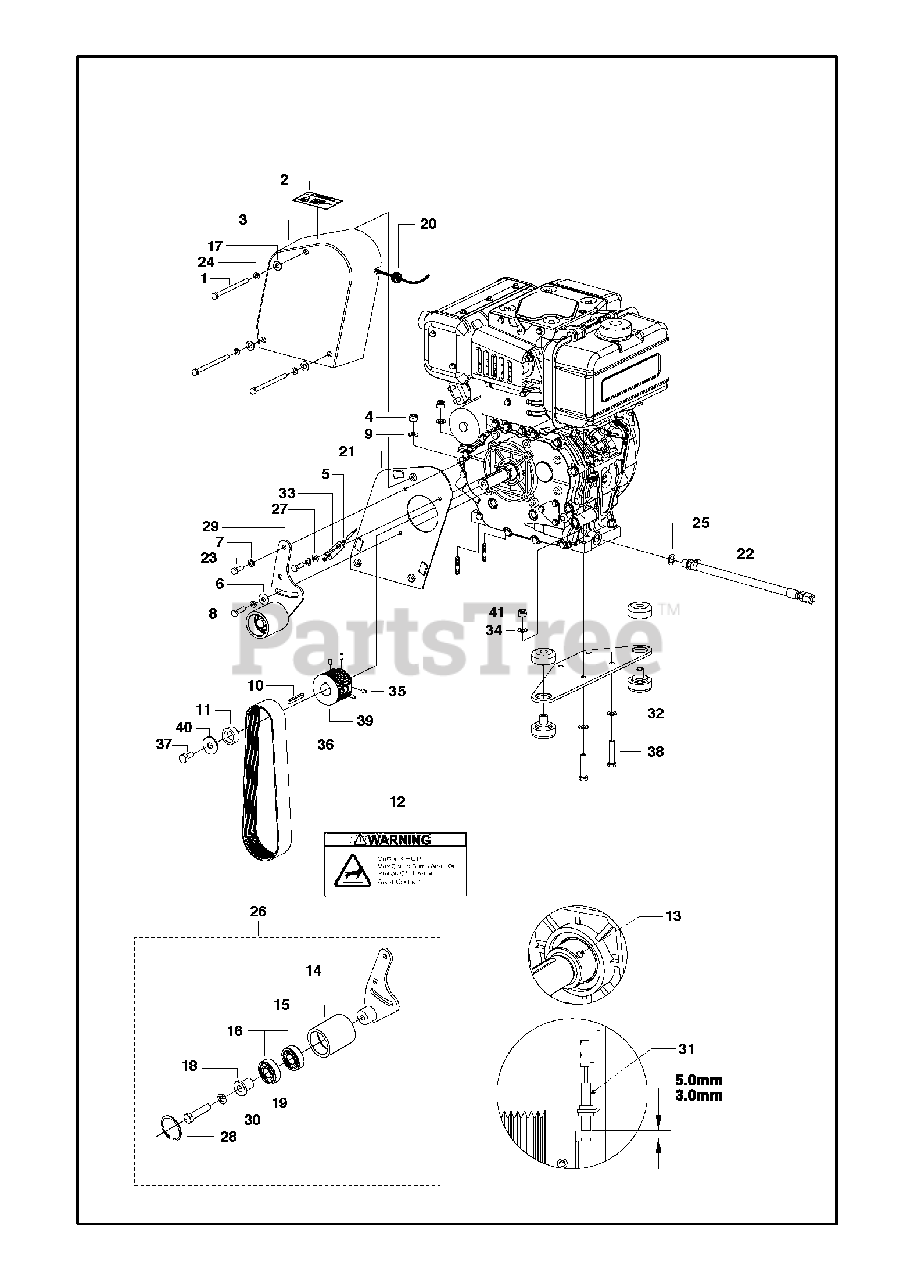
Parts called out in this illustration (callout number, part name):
4	HEXAGON LOCKING NUT
7	SPRING WASHER
9	WASHER
17	WASHER
24	SPRING WASHER
26	IDLER SHEAVE ASSEMBLY
27	WASHER
29	IDLER SHEAVE ASSEMBLY
32	WASHER
34	WASHER
41	HEXAGON LOCKING NUT
